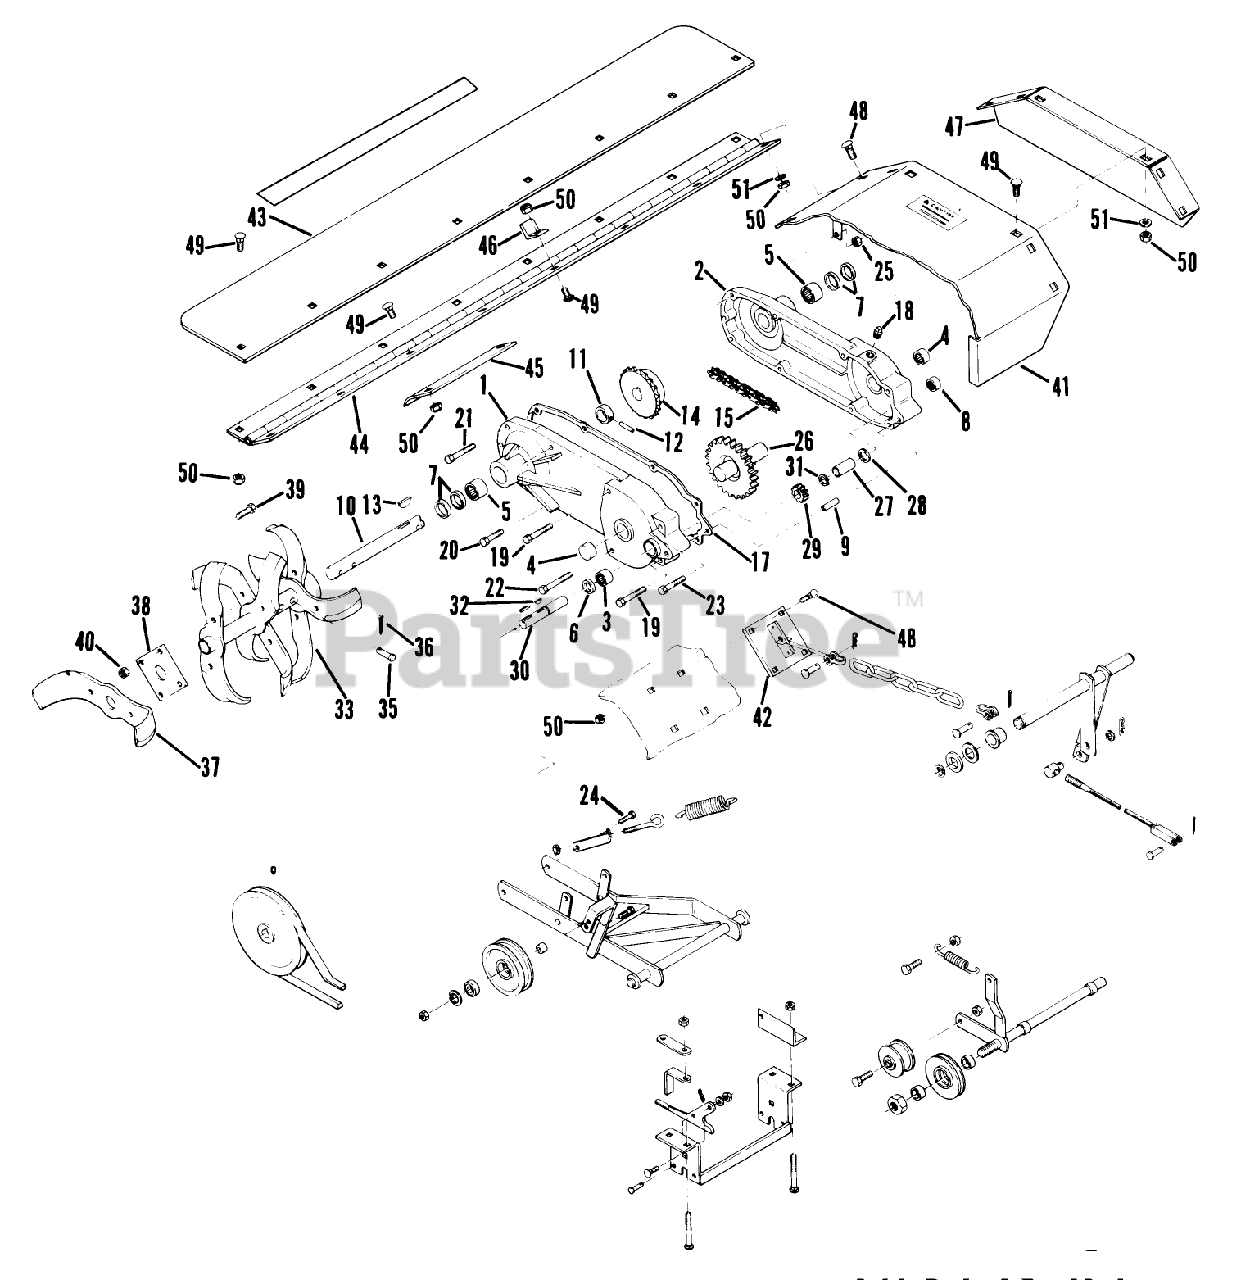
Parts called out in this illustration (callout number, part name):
1	R.H. Case (w/Bearings)
2	L.H. Case (w/Bearings)
3	BEARING-NEEDLE
4	BEARING-NEEDLE
5	BEARING-NEEDLE
6	SEAL-OIL
8	BEARING-NEEDLE
9	ROLL PIN 3/8 X 1
10	Shaft-Tine
11	Spacer
12	ROLL PIN 5/16 X 2
13	#128 Woodruff Key
14	Sprocket 20T
15	CHAIN
17	Gasket
18	SOLID PIPE PLUG
19	H H C S
20	Bolt
21	HHCS
22	BOLT
23	Hex Bolt
24	Bolt 3/8-16 x 4
25	NUT
26	Gear-Reduction
26	Reduction Gear
26	Shaft
27	Spacer
28	WASHER-THRUST
29	GEAR-PINION
30	SHAFT-INPUT
31	RING-SNAP, EXTERNAL
32	Key
33	Tine R.H.
33	Tine L.H.
35	PIN-CLEVIS
37	R.H. Tine
37	L.H. Tine
38	Plate-Tine Mounting
39	H H C S
40	Nut
41	Tiller Tine Shield
42	Lift Plate
43	Rear Shield
44	Hinge
45	Lower Tine Guard Stop
46	Stop Bracket
47	Cover-End
48	Bolt
49	CARRIAGE BOLT -4
50	Nut
51	WASHER 5/16 SAE
